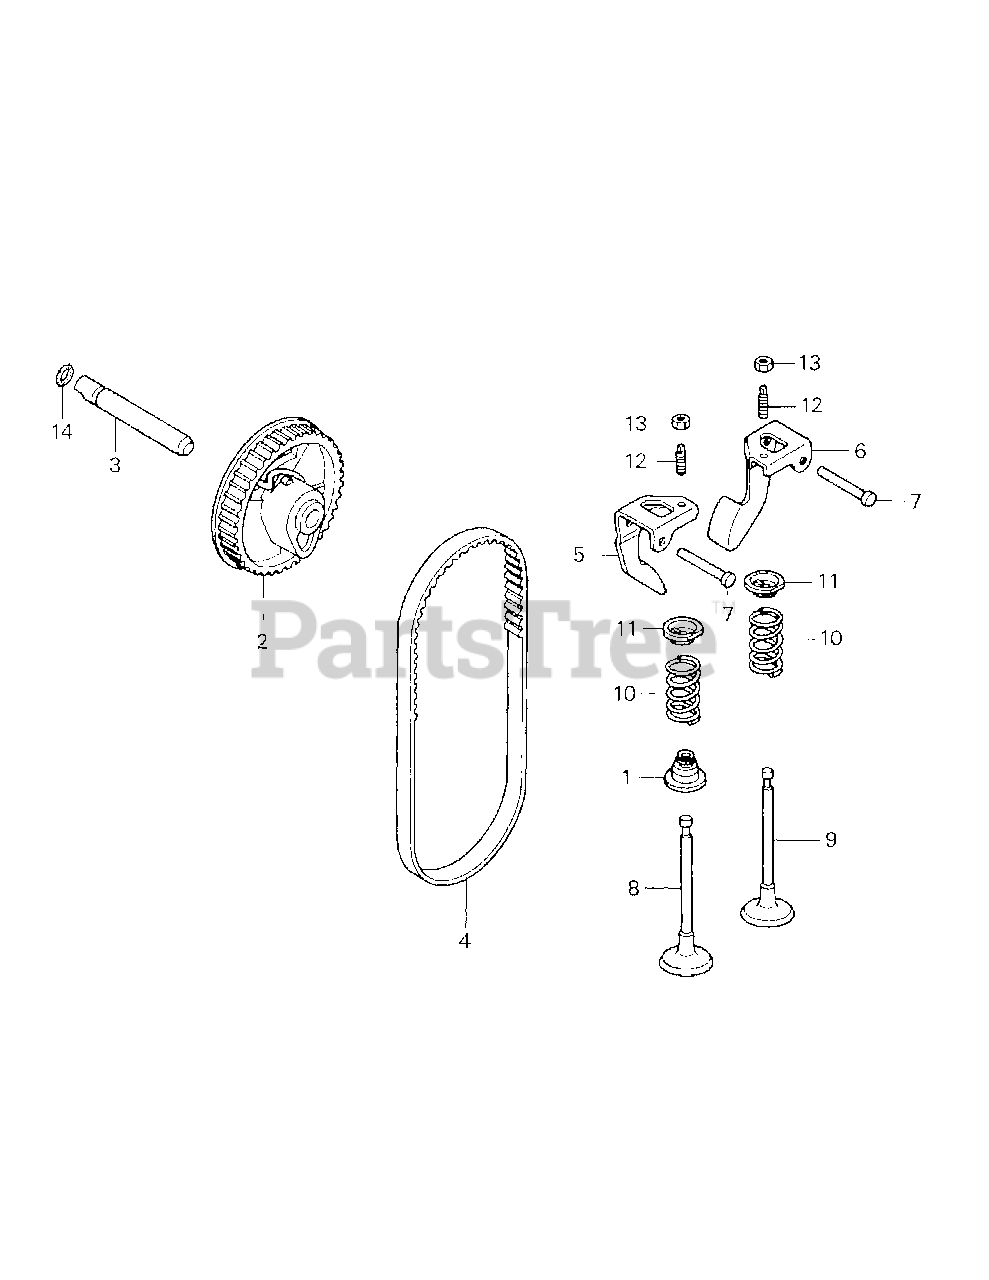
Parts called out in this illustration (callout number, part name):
1	Valve Stem Seal
2	Cam Pulley
3	Cam Pulley Shaft
4	Timing Belt, 84HU& G-200
5	Internal Valve Rocker Arm
6	External Valve Rocker Arm
7	Rocker Arm Shaft
8	Internal Valve
9	External Valve
10	Valve Spring
11	Internal Valve Spring Retainer
12	Tappet Adjustable Screw
13	Tappett Adjustble Nut
14	O-Ring, 6.8 x 1.9
